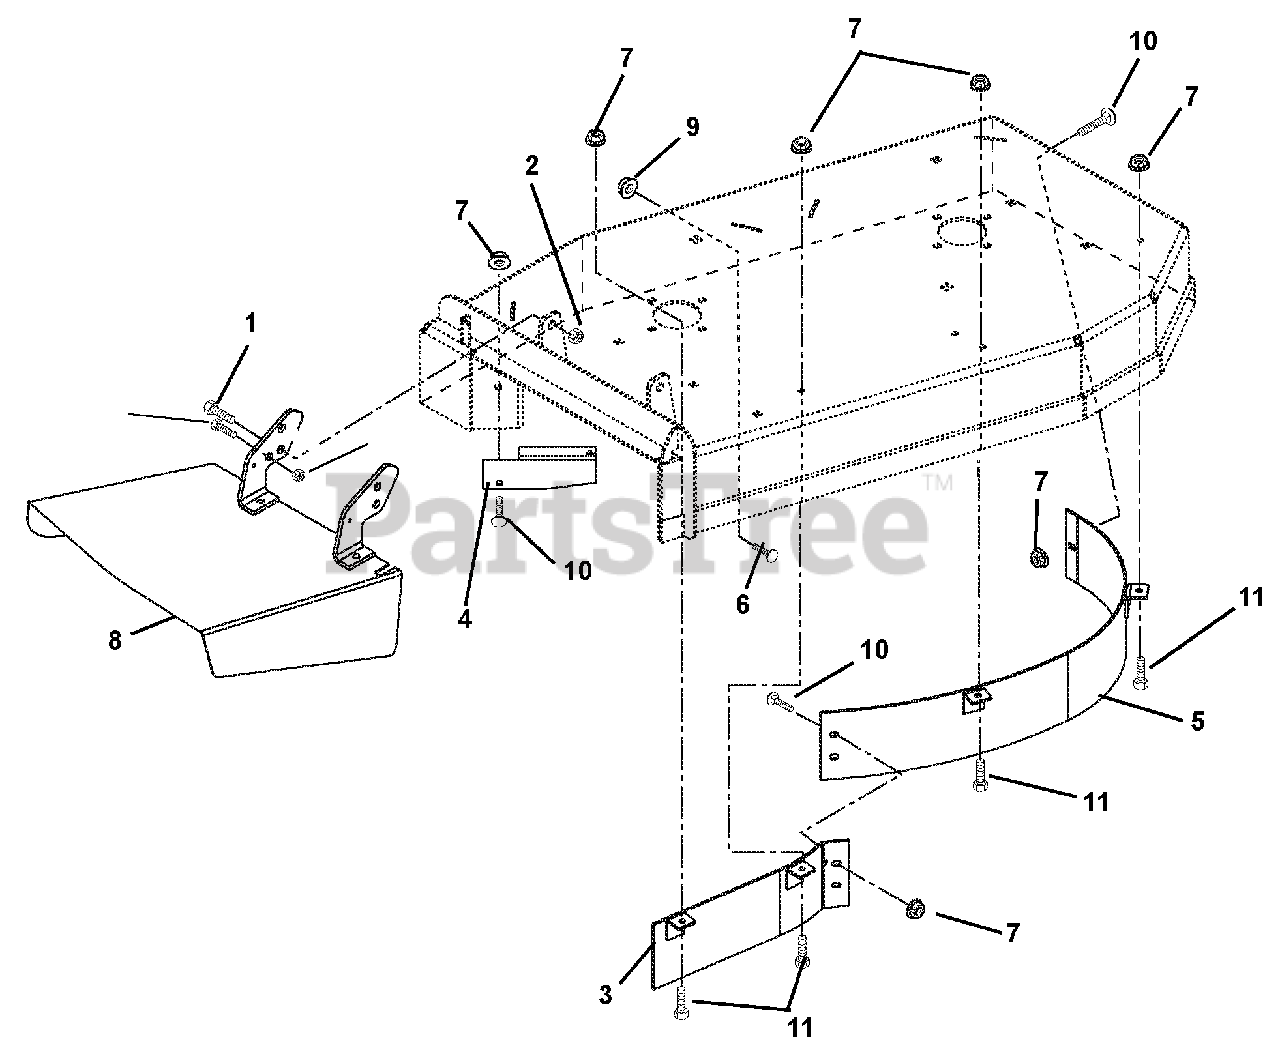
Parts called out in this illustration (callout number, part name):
1	Bolt, Hex .50-13 x 1.25 Grade 5
2	Nut, Locking-Nylon .50-13
3	Baffle, Right Front 36"
4	Deflector 32"
5	Baffle, Left Front 36"
6	Bolt, Round Head Square Neck .38-16 x 1.00 Grade 5
7	Nut, Locking-Top-Flange .31-18
8	Chute, Discharge
9	Nut, Locking-Top-Flange .38-16
10	Bolt, Round Head Square Neck .31-18 x .75 Grade 5
11	Bolt, Hex .31-18 x .75 Grade 5
